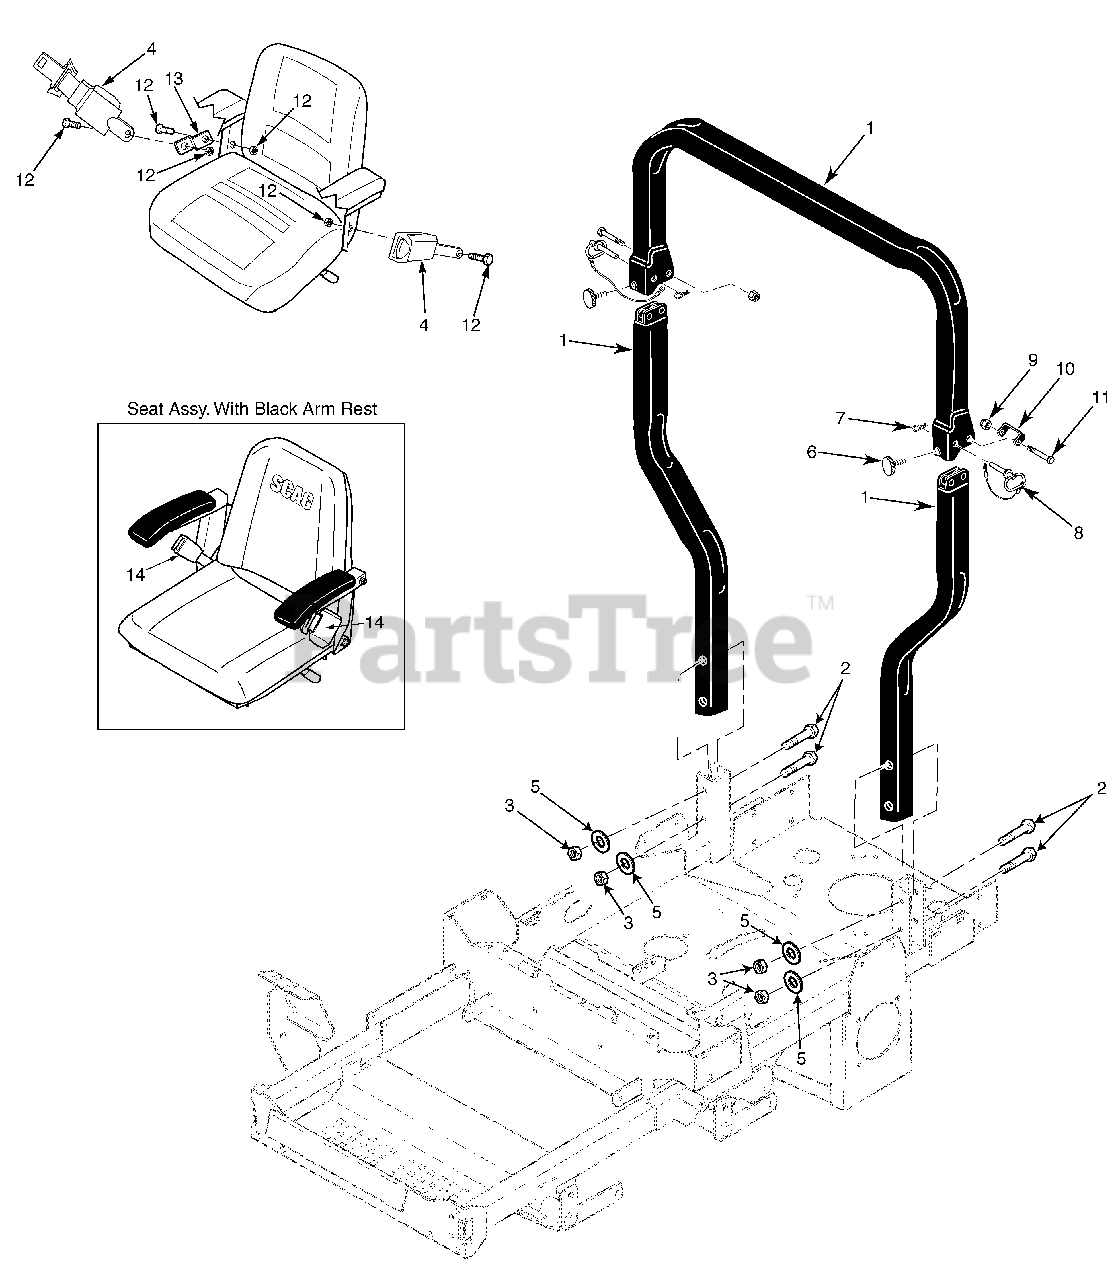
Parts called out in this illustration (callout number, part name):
1	STC Foldable ROPS Accessory
2	Bolt, Hex Head 1/2-13 x 3-1/2"
3	Nut, Center Lock 1/2-13
4	Retractable Seat Belt
5	Flatwasher, 1/2-.562 x 1.375 x .109
6	Thumb Screw, 5/16-18 NC x 3/4"
7	Hair Pin, Cotter
8	Pin
9	Nut, Center Lock 1/2-13
10	Bracket, Stop
11	Bolt, Hex Head 1/2-13 x 3-1/2"
12	Seat Hardware Kit, STC
13	Bracket
14	Retractable Seat Belt
